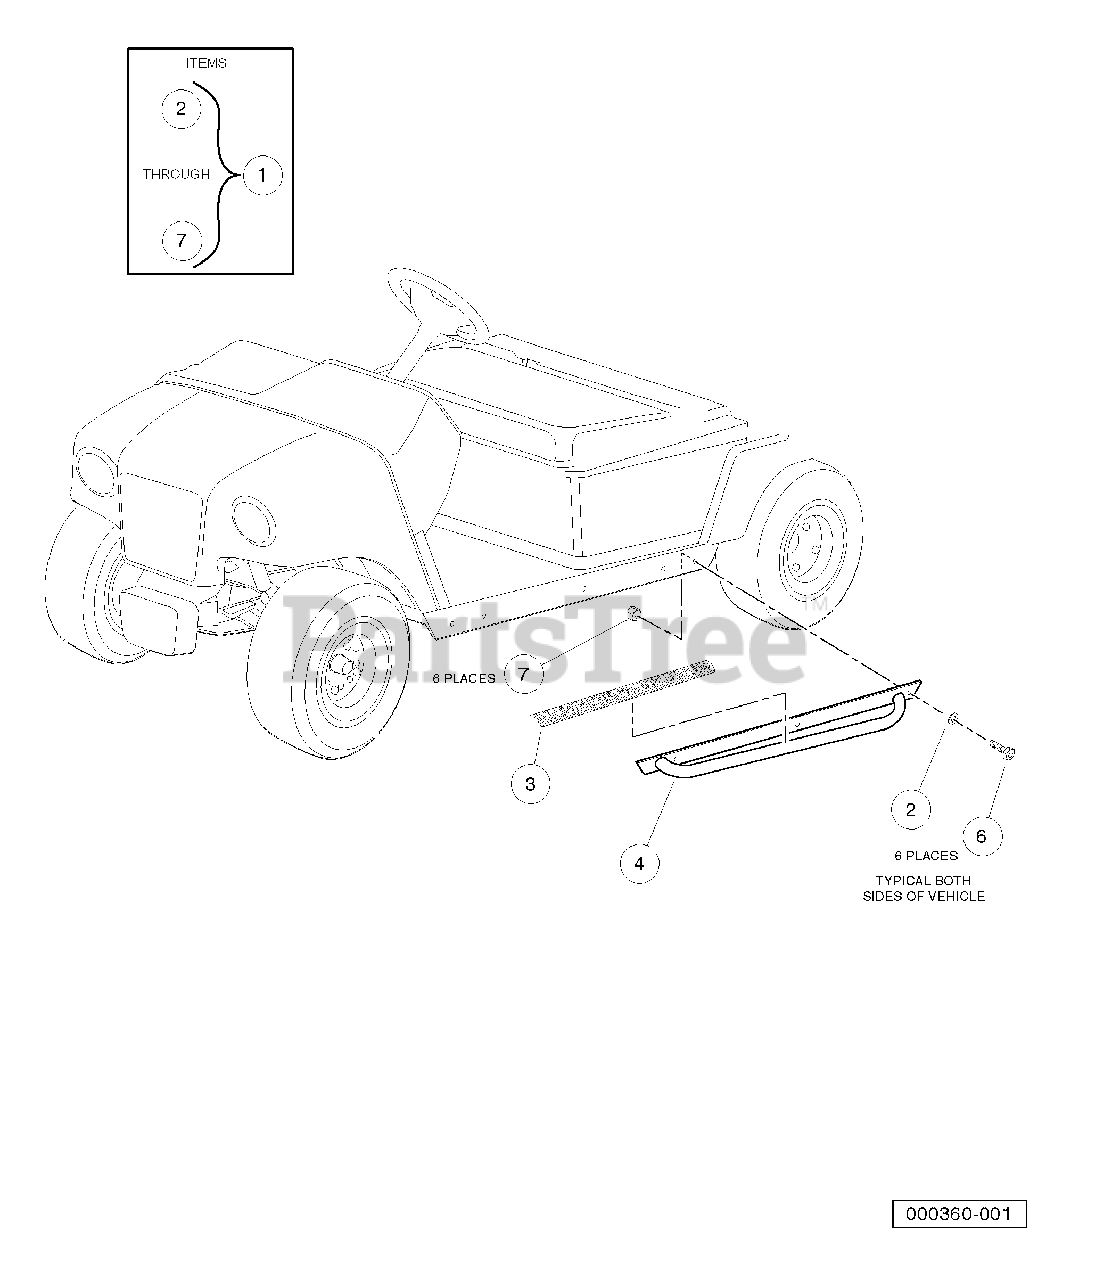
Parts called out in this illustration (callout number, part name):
1	Kit, Nerf Bar
2	Washer, 3/8 Flat
3	Tape, Non-skid
4	Asm, Nerf Bar, Driver
5	Asm, Nerf Bar, Passenger
6	Screw, 3/8-16 X 1.00 Hex-Head Cap
7	Locknut, 3/8-16 Hex
